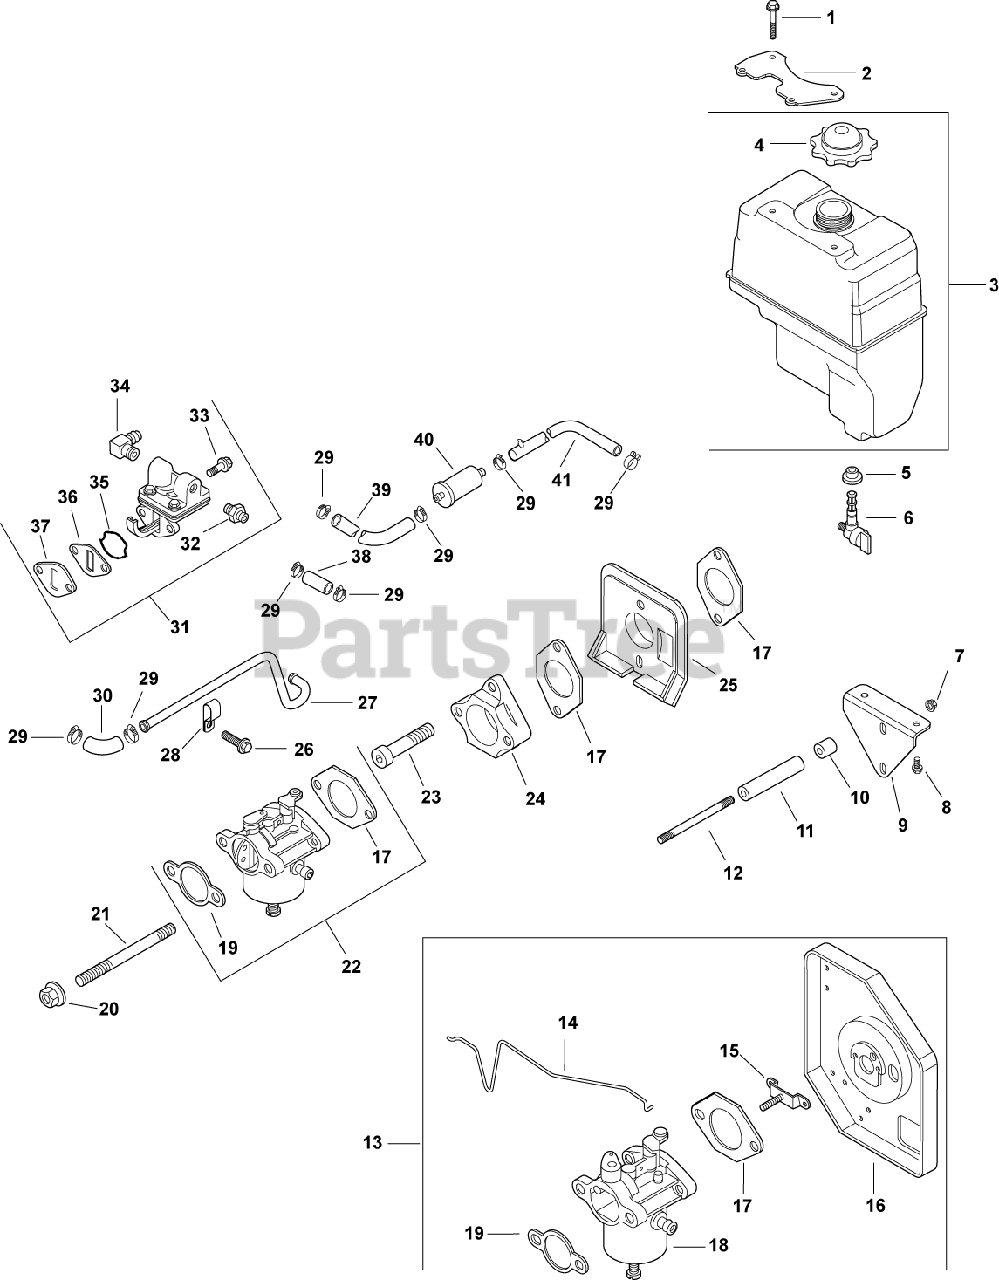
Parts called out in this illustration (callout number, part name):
1	SCREW,FLG THD FRM M6X1.0X25-(#25086395S)
2	BRACKET, FUEL TANK
3	KIT, FUEL TANK
4	CAP, FUEL TANK
5	BUSHING, FUEL TANK
6	VALVE, FUEL SHUT-OFF
7	NUT, FLG M8X1.25
8	SCREW, FLG M6X1.0X12
11	SPACER, FUEL TANK
12	STUD, M8X1.25X133-USE 25 755 54-S
13	KIT, CARB. RETROFIT
14	LINKAGE, CHOKE
15	BRACKET, AIR CLEANER
16	BASE, AIR CLEANER
17	GASKET, CARBURETOR
18	CARBURETOR W/GASEKTS - USE 12 853 139-S
19	GASKET, AIR CLEANER BASE
20	NUT, FLG M6X1.0
21	STUD,M6X1.0X116
22	KIT, CARBURETOR w/GASKETS
23	SCREW, SKT CAP M6X1.0X35
24	ADAPTER, CARBURETOR
25	DEFLECTOR, HEAT
26	SCREW, FLG THD FRM M5X.8X10
27	LINE, FUEL - DISCONTINUED
28	CLIP, TUBE & WIRING (KM)
29	CLAMP, HOSE (KM)-USE 25 237 31-S
30	HOSE, FUEL LOW-PERMEATION
31	KIT, FUEL PUMP
32	KIT, STRAIGHT FITTING
33	SCREW,FLG THD FRM M6X1.0X20-(#25086396S)
34	CONNECTOR, 90 DEG. HOSE
35	O-RING, FUEL PUMP
36	SPACER, FUEL PUMP
37	GASKET, FUEL PUMP
38	LINE - DISCONTINUED
39	LINE, FUEL 2" PUMP-FILTER
40	FILTR,FUEL 75 MICRON (GRAVTY FEED)
41	LINE, FLEXIBLE FUEL
